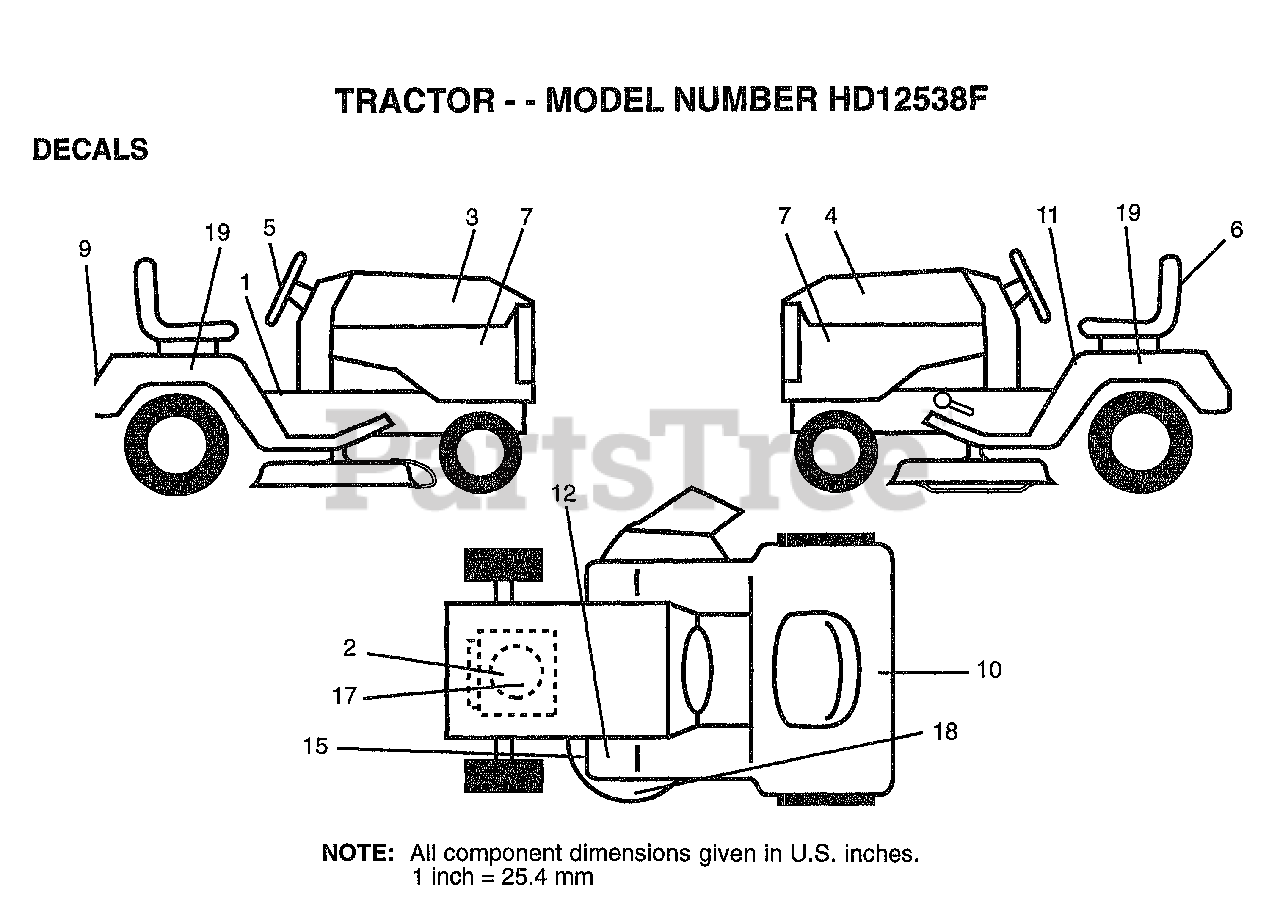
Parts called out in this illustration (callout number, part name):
2	DECAL, HP ENGINE
3	DECAL.HOOD.RH.
4	DECAL.HOOD.LH
5	DECAL, INS STRG WH
7	DECAL.PANEL.SD.SP
9	DECAL.FENDER.LOGO
10	DECAL.BATRY.3-3908
11	"DECAL FENDER,DANG"
12	DECAL CLUT/BRAKE
15	DECAL
17	DECAL.ENGINE.REPL
18	DECAL.MOWER.HOME
19	DECAL.FEND.SD.5SP
